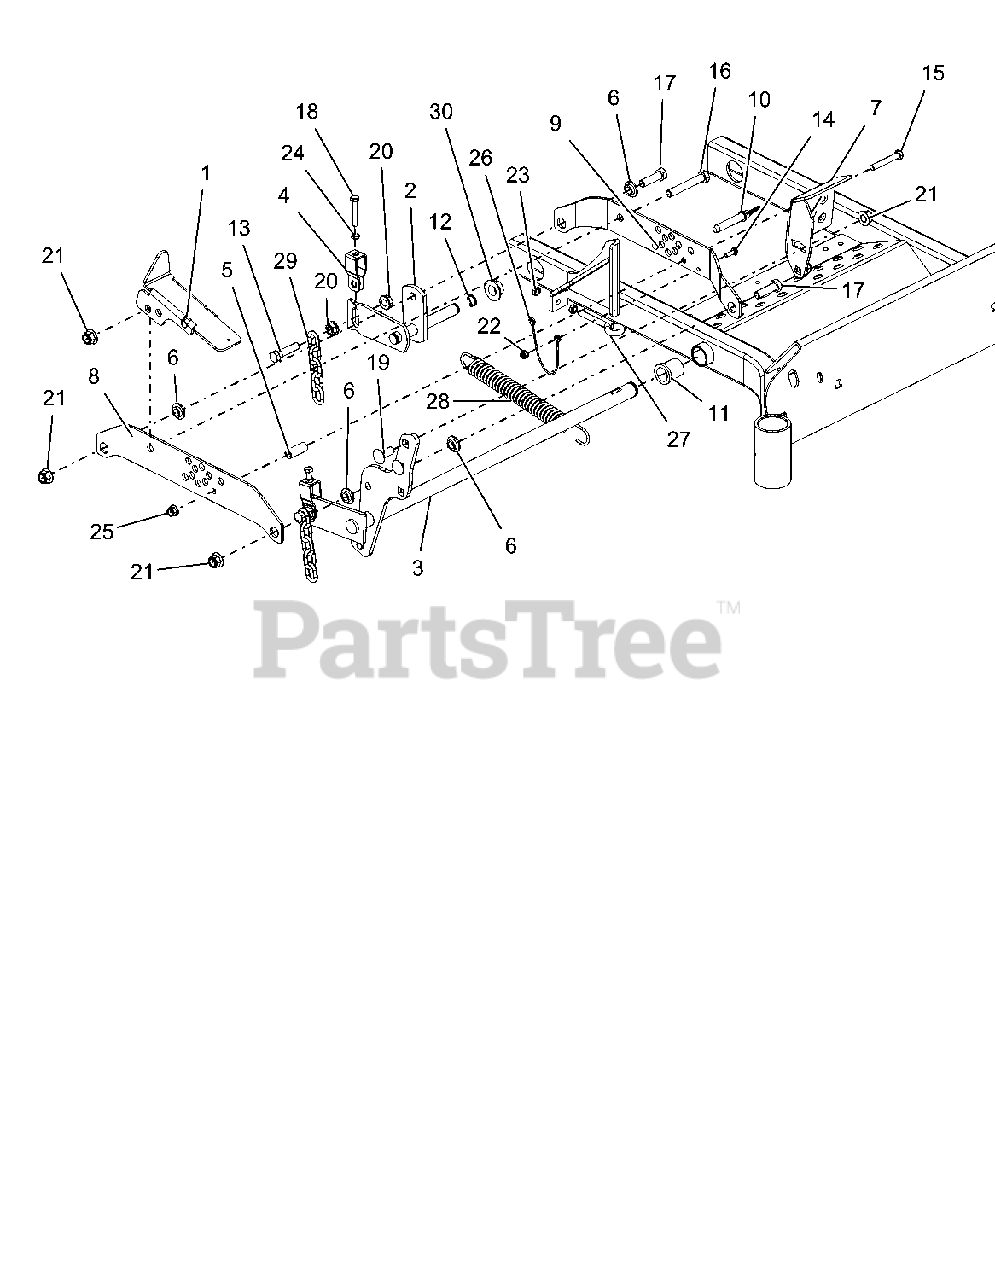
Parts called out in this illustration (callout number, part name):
1	WLDMT, MECHANICAL LOCK-UP-BLACK
2	WLDMT, REAR RH DECK LIFT ARM
3	WLDMT, FRONT RH DECK LIFT ARM
4	BRKT, DECK LEVELING
5	SPACER, .375 X .625 X 1.54
6	BSHG, FLANGE .515X.750X.31X1.12
7	PEDAL, ADJUSTABLE FOOT LIFT
8	RH OUTBOARD LIFT/HOC BRKT - BLK
9	RH INBOARD LIFT/HOC - BLK
10	PIN, .500 x 2.000 USABLE LG BALL
11	BSHG-FLG 1.00X1.25X1.5X1.5
12	RG-RTNG-EXT .750x.078
13	BLT, HEX M12-1.75X50 CLS8.8 YZ
14	BLT-HEX .25-20X.75 GR5 YWZC
15	BLT-HEX .38-16X2.50 GR5 YWZC
16	BLT-HEX .50-13X3.25 GR5 YWZC
17	BLT-HEX .50-13X1.75 GR5 YWZC
18	BLT-HEX .31-18X2.00 FTH GR5 YWZC
19	BLT-RDHDSQNK .50-13X1.25 G5 Y
20	NUT, SPLK -FLG M12-1.75 YZ
21	NUT-LK-NYL-FLG .50-13 YWZC
22	NUT-LK-NYL-FLG .25-20 YWZC
23	NUT, JAM .375-16 YWZC
24	NUT, JAM .312-18 YWZC
25	NUT-LK-NYL-FLG .38-16 YWZC
26	LANYARD, 12"
27	BOLT, EYE .375-16
28	SPRG, TENSION .162 X 1.250 X 8.250
29	CHAIN, MOWER LIFT
30	BSHG-FLG .762X1.0X.580X1.48 NY
